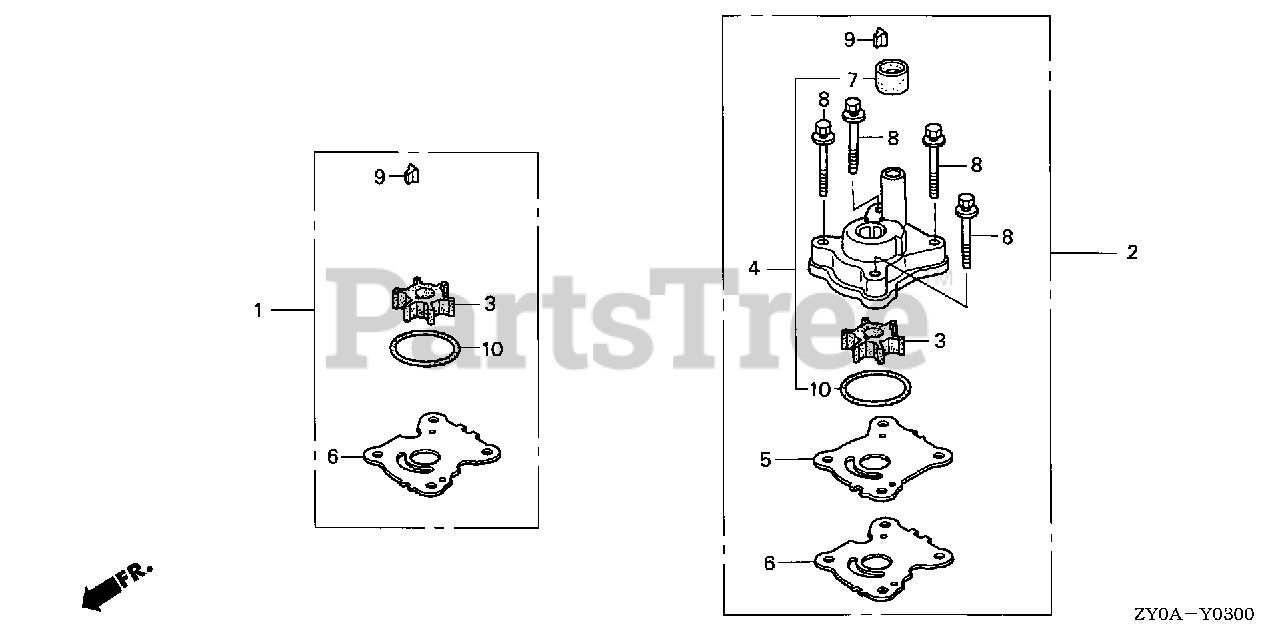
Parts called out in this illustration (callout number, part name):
1	PUMP KIT, IMPELLER
2	PUMP KIT, IMPELLER
3	IMPELLER, PUMP (UL)
4	HOUSING ASSY., IMPELLER
5	COVER, IMPELLER
6	GASKET, IMPELLER
7	RING, WATER TUBE SEAL
8	BOLT-WASHER (6X50)
9	KEY, WOODRUFF
10	O-RING (42.2X2.4)
